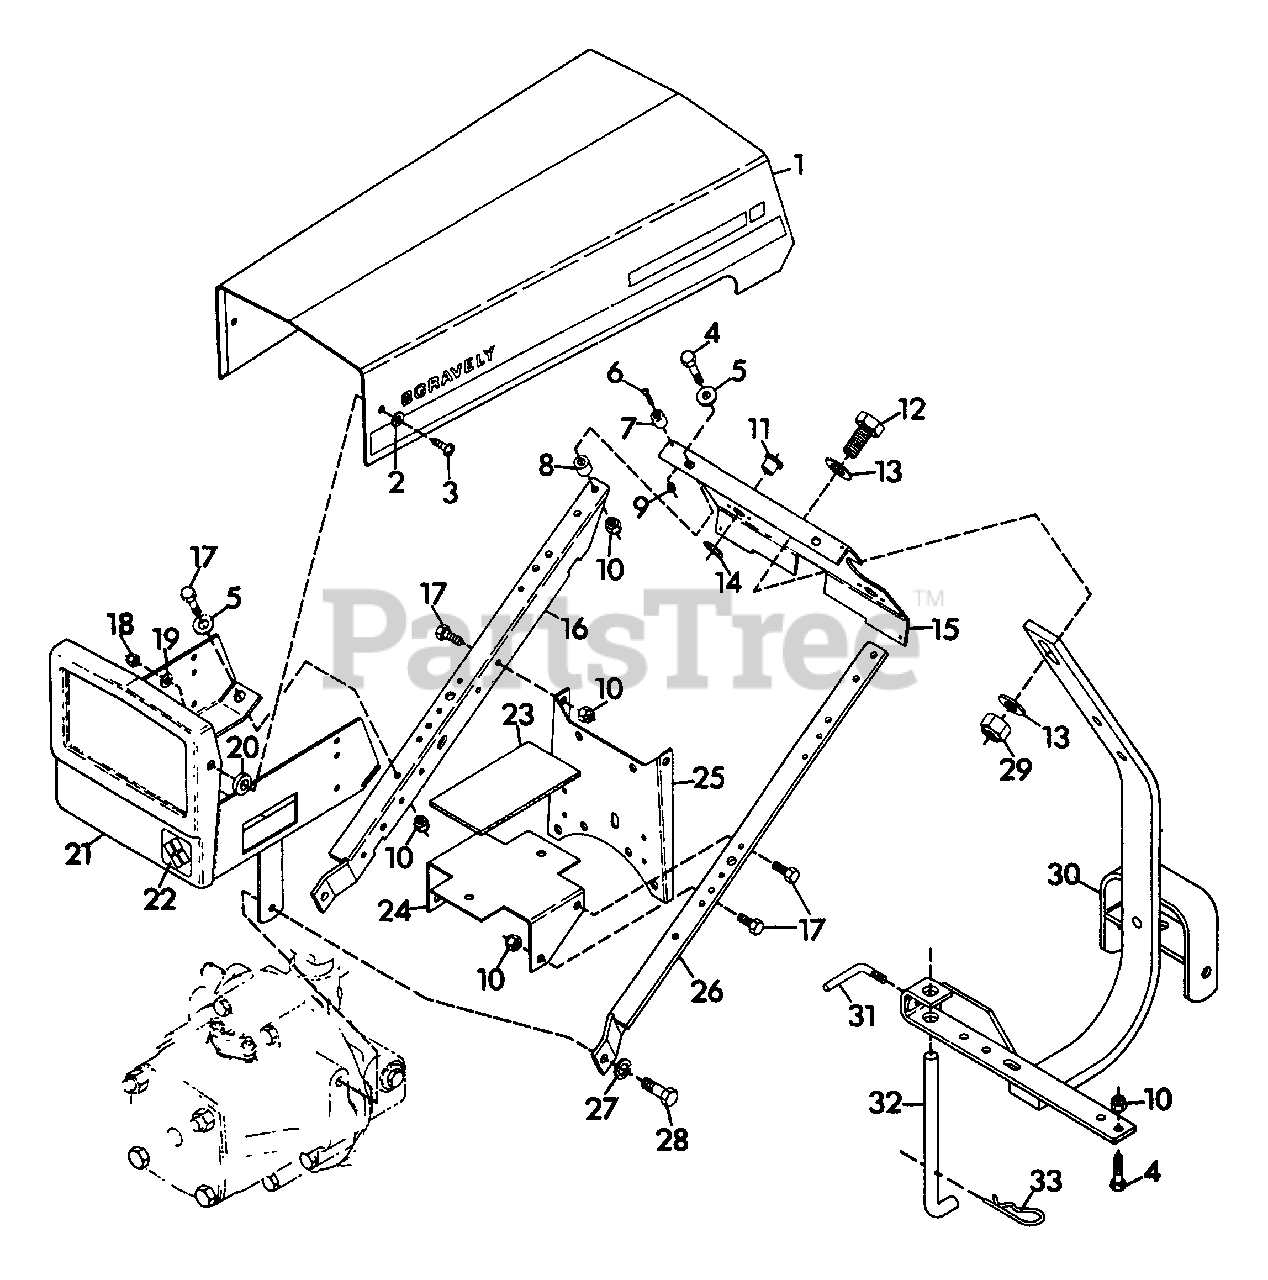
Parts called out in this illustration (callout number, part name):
1	Assembly, Hood
2	Washer, Flat .281 x .625 x .065
3	Screw, Machine 1/4-20 x 1.00 PHD
4	Bolt, Hex 3/8-16 x 1.50
5	Washer, Flat .406 x .812 x .065
6	Screw, Machine 6-32 x .625 PHD
7	Bumper
8	Bushing, Reverse Idler
9	Nut, Machine Lock 6-32
10	Nut, Lock 3/8-16
11	Bushing, .513 x .750 x .625
12	Bolt, Hex 5/8-11 x 2.00
13	Washer, Flat .656 x 1.250 x .100
14	Ring, Retaining
15	Plate, Silk Screen (Manual Start)
15	Plate, Silk Screen (Electric Start)
16	Support, Handlebar R.H.
17	Bolt, Hex 3/8-16 x .875
18	Nut, Lock 1/4-20
19	Washer, Flat .313 x .875 x .065
20	Bushing, Hood
21	Weldment, Battery Bracket
22	Decal
23	Pad, Gas Tank
24	Bracket, Tank Support
25	Bracket
26	Support, Handlebar L. H.
27	Washer, Lock 1/2 Reg.
28	Bolt, Hex 1/2-13 x 1.00
29	Nut, Lock 5/8-11
30	Weldment, Hitch 10 and 12 Hp
31	Handle, Adjusting
32	Stand, Kick
33	Pin, Hair
